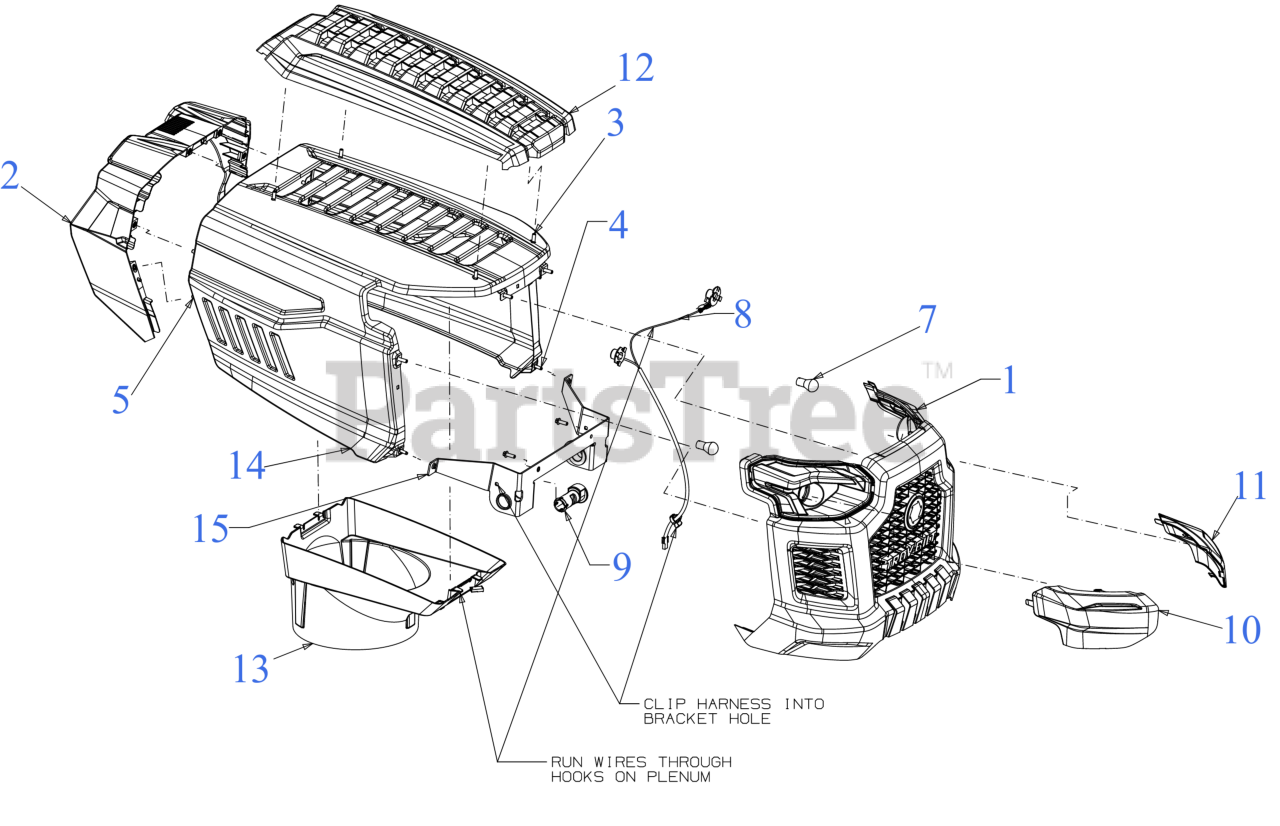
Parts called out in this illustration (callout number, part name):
1	FRONT GRILLE
2	DASH COLLAR ASSEMBLY
2	SQUARE NUT 1/4-20
3	SCREW 1/4 x .750
4	SCREW M6-1 x .625
5	SCREW 1/4-20X.5 GR5
7	MINIATURE LAMP-12V #1156
8	HEADLIGHT HARNESS
9	HOOD PIVOT PIN
10	HEADLIGHT LENS (RH)
11	HEADLIGHT LENS (LH)
12	HOOD SCOOP
13	HOOD PLENUM (B STYLE)
